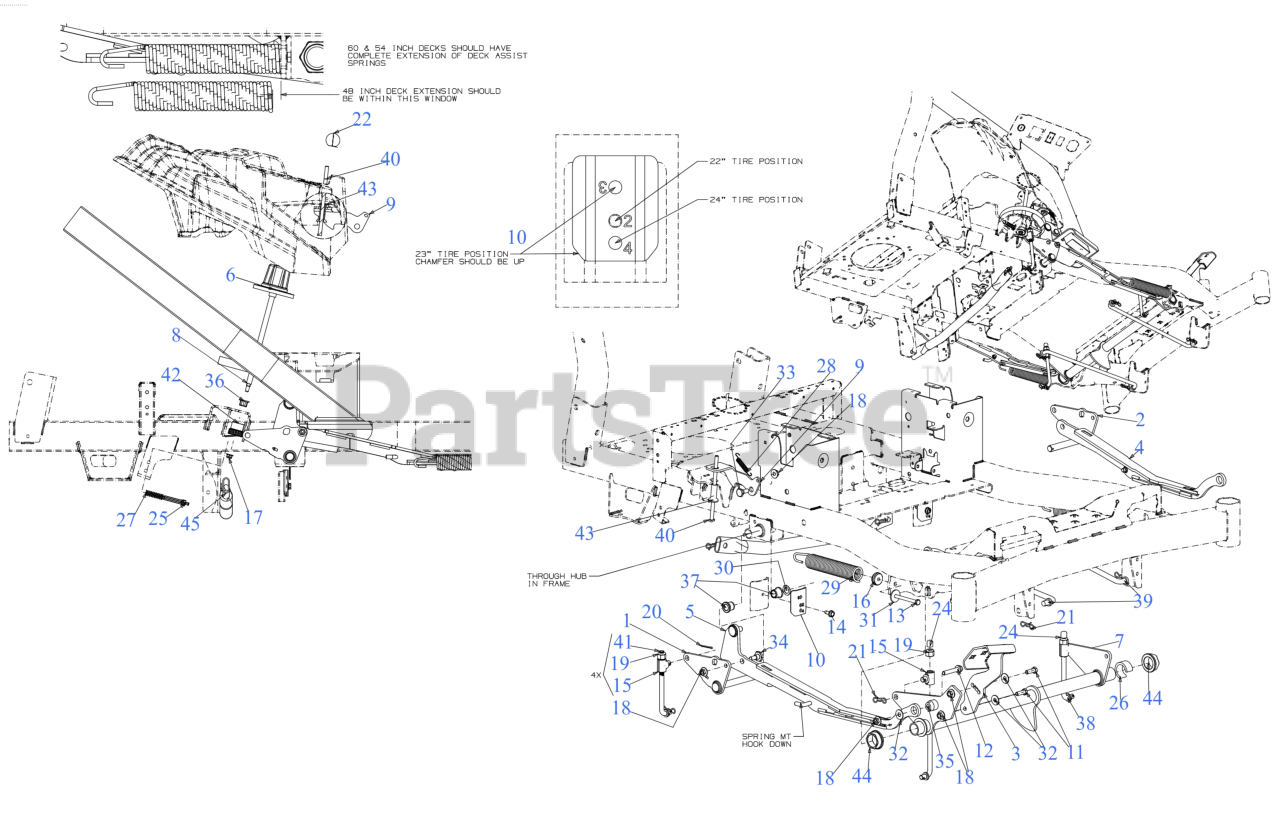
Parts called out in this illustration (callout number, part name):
1	BELLCRANK BRACKET (RH)
2	BELLCRANK BRACKET (LH)
3	DECK LIFT PEDAL
4	LIFT LINK (LH)
5	LIFT LINK (RH)
6	DECK HEIGHT ADJUSTMENT KNOB
7	LIFT TUBE (FRONT)
8	DECK HEIGHT ADJUSTMENT ROD
9	TRAVEL LOCK PLATE
10	UPSTOP BRACKET
11	SCREW 3/8-16 x 1 GR5
12	SCREW 3/8-16 x 2.00 GR5
13	SCREW 5/16-18 x 3.50 GR5
14	SCREW 5/16-18 x .750
15	LIFT ROD FERRULE
16	LIFT SPRING INSERT
17	FLANGE LOCK NUT 5/16-18
18	FLANGE LOCK NUT
19	HEX LOCK NUT NYLON
20	COTTER PIN
21	BOW TIE COTTER PIN
24	LIFT ROD END CAP
25	DETENT PLUNGER
26	LIFT TUBE SPACER
27	COMPRESSION SPRING .531 OD 1.75 LG
28	EXTENSION SPRING 2.675"
29	EXTENSION SPRING
30	FLAT WASHER
31	WASHER-5/16 x 1.25X 1.27
32	WASHER-.395 x 1.0 x .62
33	SHOULDER SCREW
34	SHOULDER SCREW .50 x .385
35	SHOLUDER SPACER
36	HEX FLANGE BEARING .506ID x .590LG
37	FLANGE BUSHING
38	DECK LIFT ROD 6.875"
39	DECK CONTROL ROD
40	TRAVEL LOCK ROD
41	DECK LIFT ROD 6.562"
42	DECK HEIGHT DETENT HUB
43	LOCK ROD SLEEVE SPACER
44	FLANGE BEARING
45	DECK STABILIZER TUBE
